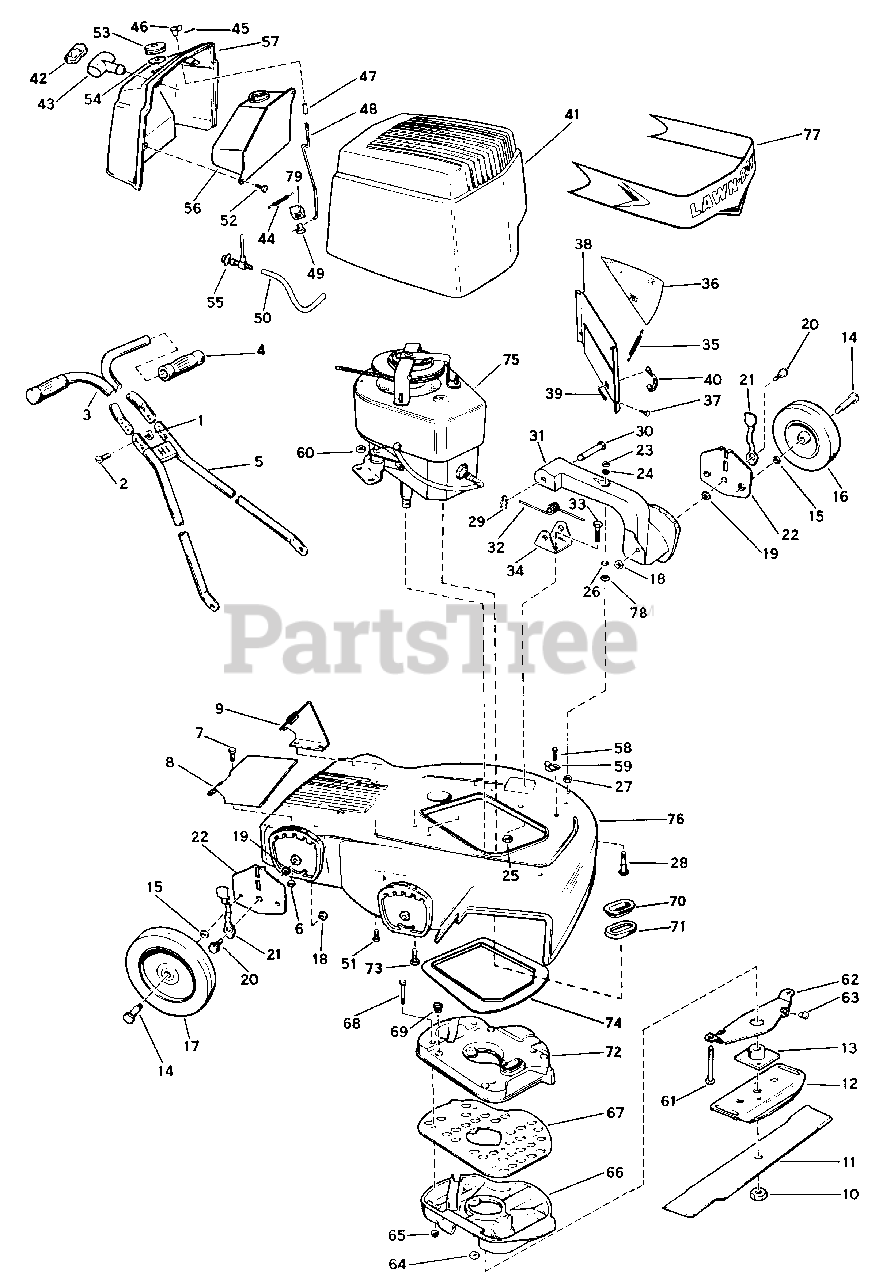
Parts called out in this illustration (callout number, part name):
1	Nut-Nylok, Handle
2	Screw-Handle
3	Handle Assembly-Top
4	Grip-Handle
5	Handle Assembly-Bottom
6	Nut-Nylok, Handle Bracket
7	Screw-Handle Bracket
8	Handle Bracket Assembly Right
9	Handle Bracket Assembly Left
10	Nut-Blade, Nylok
11	Blade, 19"
12	Blade Stiffener
13	Collar and Plate Assembly
14	Bolt-Shoulder Wheel
15	Washer-Plain (Wheel)
16	Wheel and Tire Assembly 6 x 1.50
17	Wheel and Tire Assembly 8 x 1.75
18	Nut-Nylok (Wheel Lever Shoulder Bolt)
19	Washer-Shoulder Bolt, Wheel Lever
20	Bolt-Shoulder, Wheel Lever
21	Spring-Wheel Adjustment
22	Lever-Wheel Adjustment
23	Nut-Level Ride Shoulder Bolt
24	Washer-Level Ride, Fiber
25	Nut-Nylok, Level Ride Bracket
26	Washer-Level Ride, Rubber
27	Nut-Hex, Level Ride Shoulder Bolt
28	Bolt-Shoulder, Level Ride Arm
29	Hair Pin-Level Ride Arm
30	Pin-Level Ride Arm
31	Arm-Level Ride
32	Spring-Level Ride Arm
33	Screw-Level Ride Arm Bracket
34	Bracket-Level Ride Arm
35	Spring-Sound Trap Screen
36	Screen-Sound Trap
37	Screw-Thread Cutting
38	Shield-Sound Trap
39	Pin-Cotter
40	Clip-Spring, Cover
41	Bonnet-Front
42	Anchor-Rope to Handle
43	Handle-Starter
44	Spring-Shut-off
45	Cotter Pin-Choke Knob
46	Knob-Choke Rod
47	Sleeve-Choke Rod
48	Rod-Choke
49	Pivot-Choke Rod (Nylon)
50	Hose-Gas Line
51	Screw-Thread Cutting (Rear Bonnet to Housing)
52	Screw-Thread Cutting
53	Gas Cap
54	Gasket-Gas Cap
55	Shut-off Valve Assembly
56	Gas Tank
57	Bonnet-Rear
58	Screw-Thread Cutting (Bonnet Latch)
59	Latch-Bonnet
60	Nut-Nylok, Engine Mounting
61	Screw-Engine Mtg., Long
62	Bracket-Crankshaft Limit Stop
63	Bumper-Crankshaft Limit Stop
64	Nut-Muffler to Crankcase Studs
65	Nut-Muffler
66	Muffler-Bottom
67	Gasket-Muffler
68	Bolt-Muffler
69	Spring-Muffler
70	Sleeve-Muffler Gasket
71	Gasket-Exhaust
72	Muffler-Top
73	Screw-Engine Mtg., Short
74	Seal-Dust
75	C-60 Engine
76	Housing, 19"
77	Decal-LAWN-BOY
78	Washer-Plain
79	Retainer-Choke Rod
